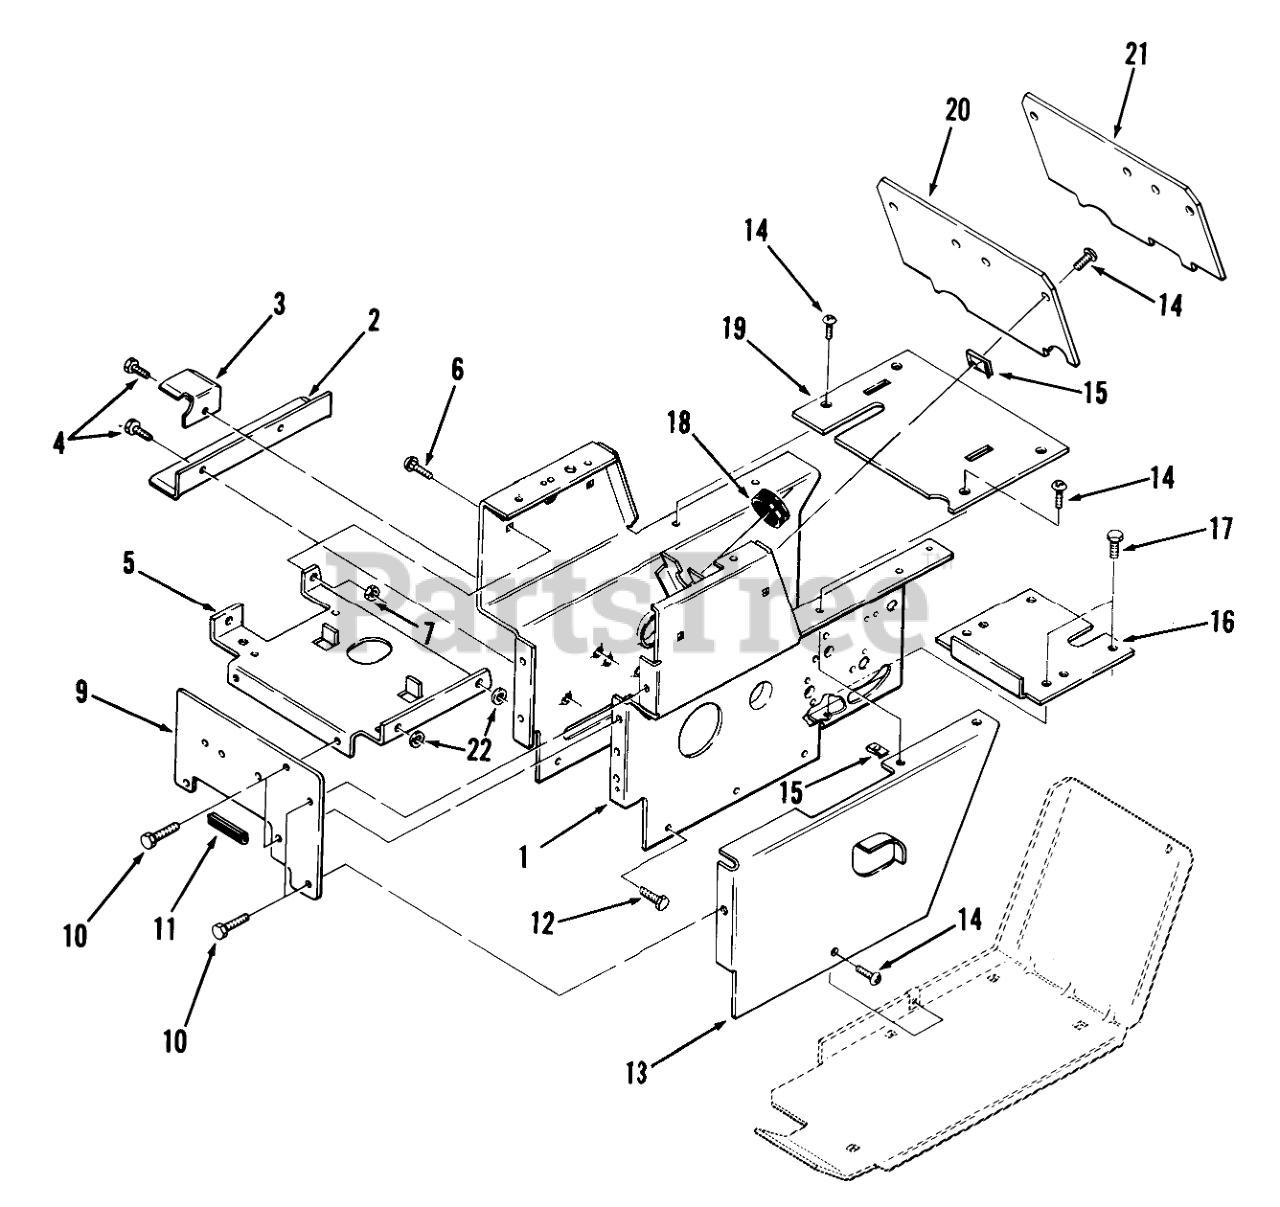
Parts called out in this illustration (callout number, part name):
1	Hoodstand
2	ANGL-BLT GURDB
3	BRCKET-BLT SUTB
3	Belt Bracket
4	SCREW
5	Battery Support Bracket
6	CARRIAGE BOLT -4
7	Nut
9	Front Plate
9	Front Plate C-161 Twin Only
10	SCREW
11	EDGE TRIM 2" 102896
12	SCREW
13	Side Cover LH
14	Screw
16	Cover-Dust
17	SCREW
18	GROMMET
19	Shift Cover Plate
19	PLATE-SHIFT PATTE B
20	PLATE-HOODSTAND REAR
21	Hood Stand Plate
22	WASHER 5/16 SAE
